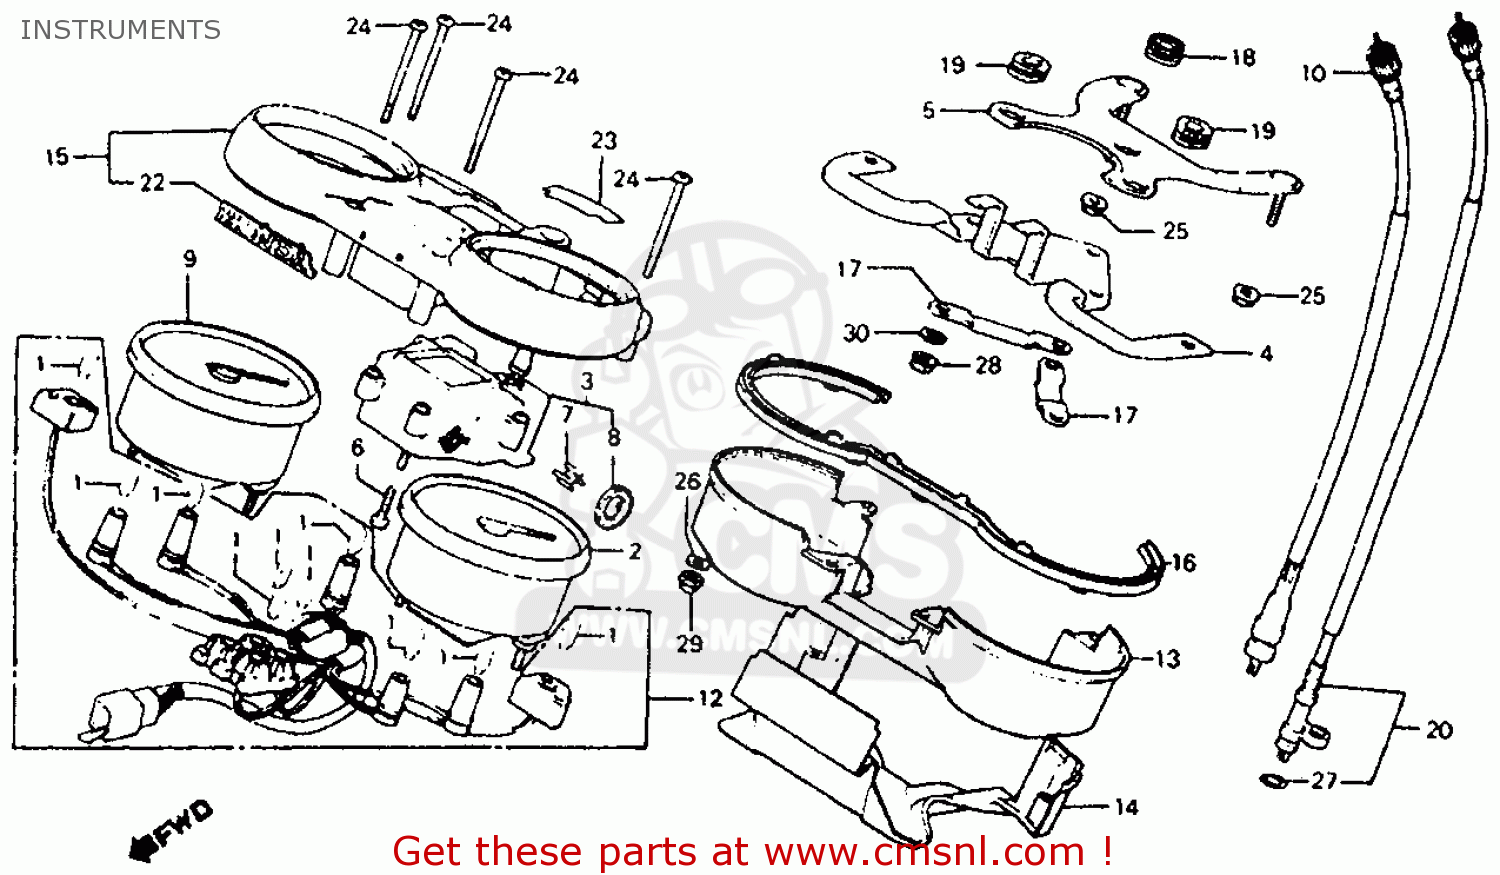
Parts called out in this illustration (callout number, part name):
1	BULB
2	SPEEDOMETER ASSY.
3	ODOMETER ASSY.
4	STAY A,METER SET
5	STAY B
6	SCREW,PAN,4X20
7	JOINT.ODOMETER
8	RUB,SUB COMB.MET
9	TACHOMETER ASSY.
10	CABLE,TACHOMETER
12	CORD COMP.
13	COVER,METER LWR
14	COVER,METER LWR
15	COVER,METER UPPER
16	RING,METER COVER
17	CLAMP,CORD
18	RUBBER,CUSHION
19	RUBBER,CUSHION
20	CABLE ASSY,SPDMT
22	EMBLEM,METER TOP
23	LABEL,BRK.CAUTION
24	SCREW,PAN,4X45
25	NUT,FLANGE,6MM
26	WASHER,6.5X18
27	ORING,6.8X1.9
28	NUT,HEX.,6MM
29	NUT,HEX,CAP,6MM
30	WASHER,SPRING,6MM
